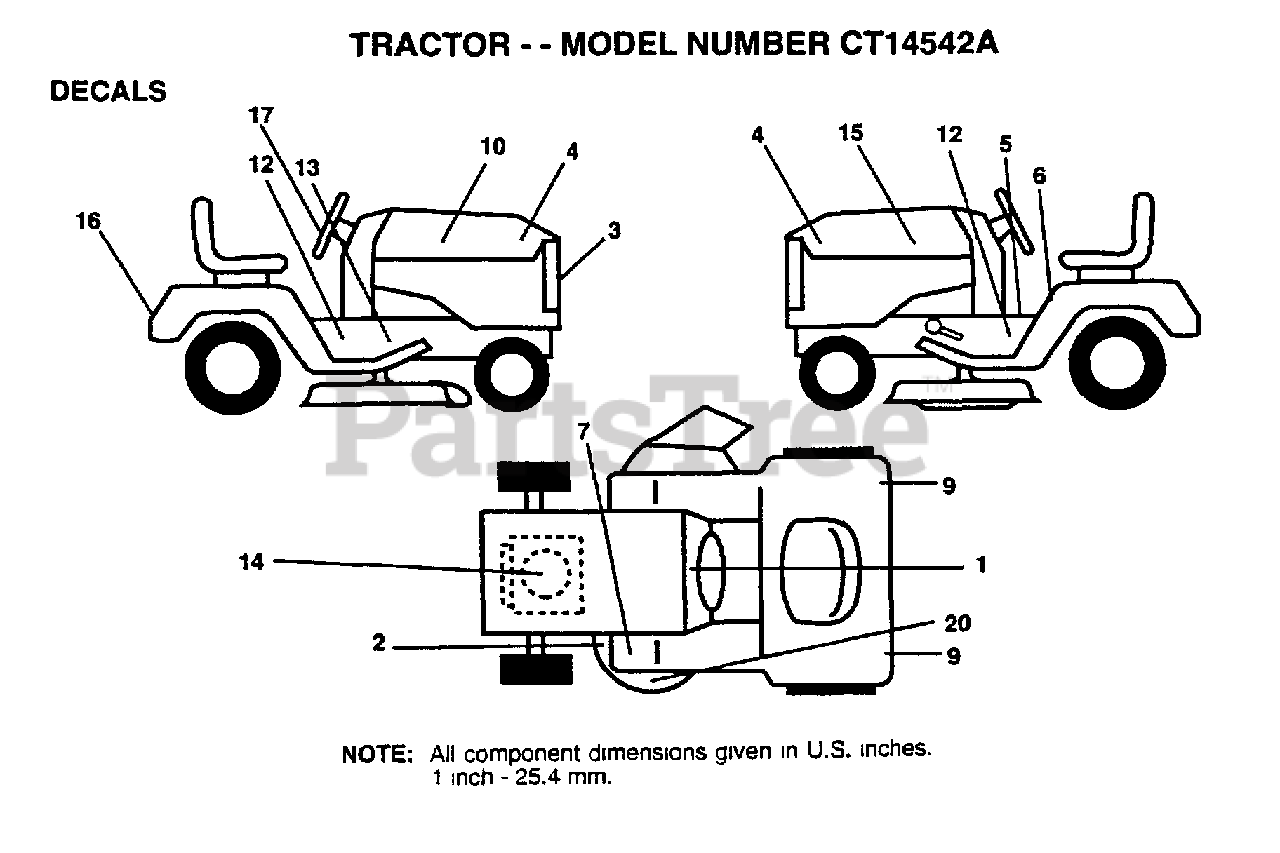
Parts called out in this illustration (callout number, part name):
1	DECAL.DASH.INST.
2	DECAL
3	DECAL.GRILLE
4	DECAL.INS.HD.RALL
5	DECAL BRAK PARK
6	DECAL
9	REFLECTOR-TAIL YT
10	DECAL.HD.RH.RALLY
12	CHASSIS DECAL
14	DECAL, ENGINE
15	DECAL.HD.LH.RALLY
16	DECAL.FENDER
17	DECAL INST STRWHL
